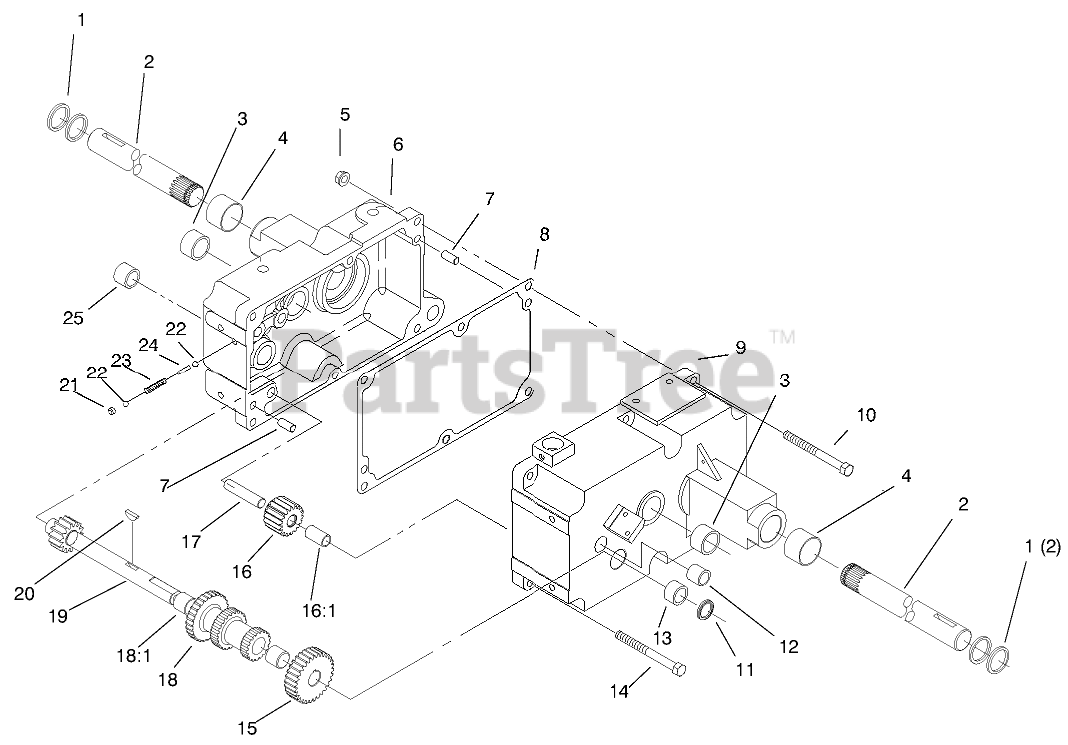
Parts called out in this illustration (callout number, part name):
1	SEAL-OIL
1	BOLT-HEX
2	AXLE-REAR
2	BEARING-BALL
3	BEARING-NEEDLE
3	WASHER
4	BEARING
4	END CAP-DIFFERENTIAL
5	NUT-LOCK, NI
5	GEAR-AXLE DIFFERENTIAL
6	CASE-RH TRANS
6	RING-SNAP
7	PIN-DOWEL
7	WASHER-THRUST
8	GASKET-TRANSMISSION
8	GEAR-DIFFERENTIAL RING, 43T
9	CASE-TRANS LH
9	GEAR ASM
10	SCREW-HH
10	GEAR-PINION, 11T
11	SEAL-OIL
12	BEARING-NEEDLE
12	PLUG-PIPE, SQH
13	BEARING-NEEDLE
14	SCREW-HH
14	RAIL-SHIFT
15	GEAR-CLUSTER SHAFT
15	RAIL-REAR SHIFT
16	GEAR/BUSHING ASM-REVERSE IDLER
16	PIN-ROLL
17	PIN-DIFFERENTIAL
17	FORK-SHIFT
18	GEAR-CLUSTER
18	BOLT-DETENT
19	SHAFT-CLUSTER
19	SHIFT FORK ASM
20	SPRING-SHIFT STOP
21	CUP-PLUG
21	BALL-DETENT
22	BALL-DETENT
22	BEARING-NEEDLE
23	SPRING-SHIFT STOP
23	Gear
24	PIN-SHIFT
24	GEAR-SHAFT REDUCTION
25	BEARING-NEEDLE
25	SHIFT ASM
26	GEAR
26:1	BEARING-NEEDLE
27	GEAR-LOW AND REVERSE
28	GEAR-HI AND 2ND
29	Gear
29	GEAR
29:1	BEARING-NEEDLE
30	GEAR-SLIDING
31	SHAFT-INPUT
32	WASHER-THR
33	BEARING-NEEDLE
34	SEAL-OIL
